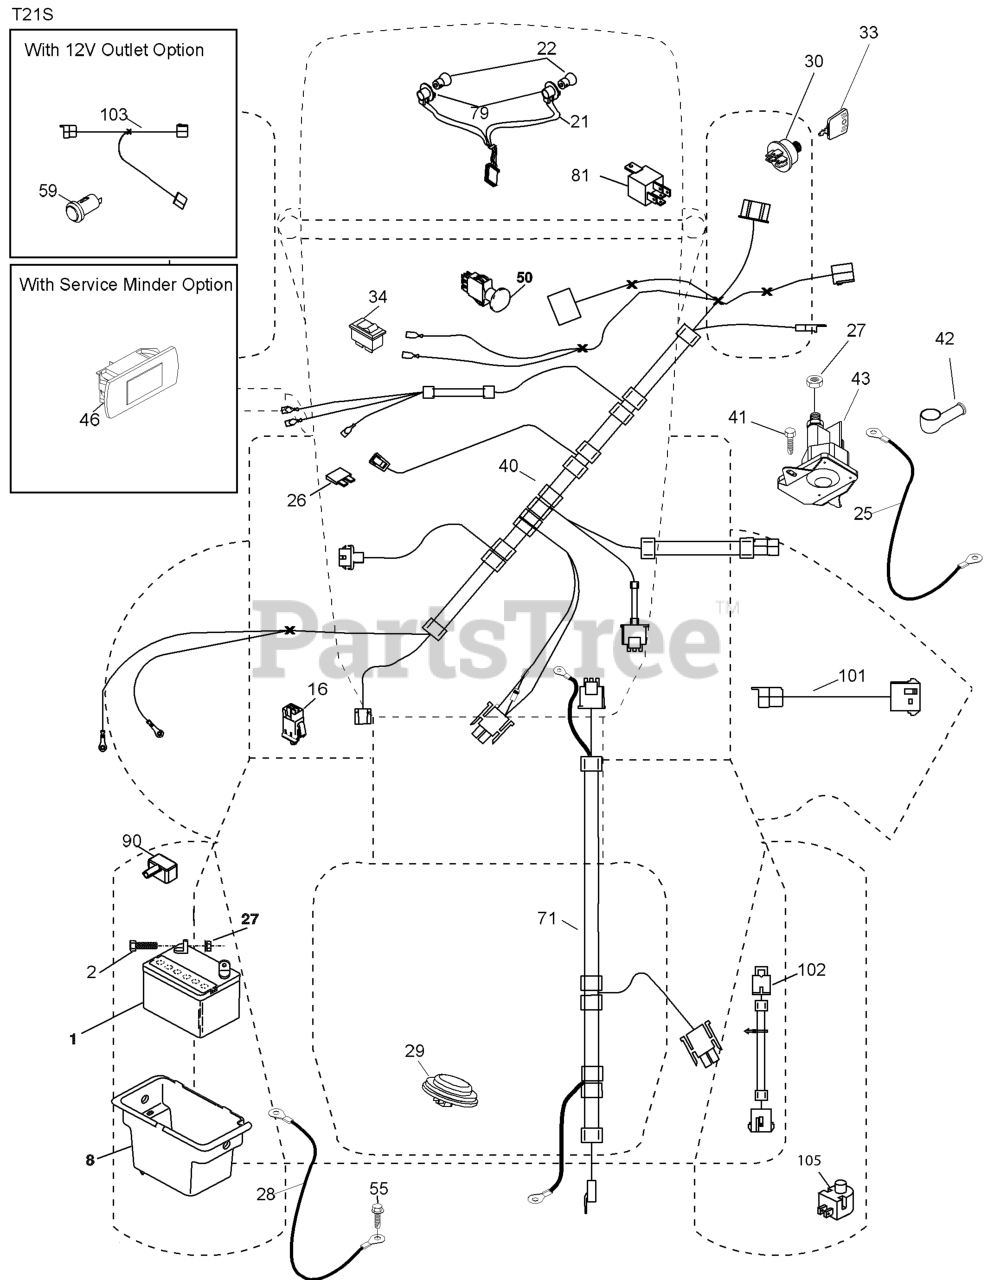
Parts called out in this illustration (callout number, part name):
1	Battery
2	BOLT.HEX.1/4.X.3/4.DICHROMATE
8	BOX.BATTERY.MNT.REAR.L
16	SWITCH INTERLOOK PUSH-IN
21	HARNESS ASSY LIGHT
25	CABLE.STARTER.6G.BL/RED.17.5
26	FUSE 20AMP
27	NUT
28	CABLE.BLACK.18"REAR.BA
29	SWITCH.SEAT.DELTA.OPC.
30	SWITCH.IGN.DELTA.W.LGH.ROS
33	KEY.CHAIN.BLISTER.PACK.GEN.INT
40	HARNESS.IGN.ELE.RELAY.TEX.46"
41	SCREW
42	TERMINAL COVER
43	SOLENOID.W/BRASS.PLUNGER
46	RP.GUAGE.SRVCMNDR.HRMTR.
50	RP.PTO.SWITCH.8 TERMINAL.BLACK
55	SCREW 5/16"
59	OUTLET.12-VOLT
71	HARNESS.IGN.CHASS.TEX.REAR.BAT
79	BULB HOLDER ASM.
81	RELAY HARNESS.SEALED
90	COVER.TERMINAL.BATTERY
101	PIGTAIL.MATNLK.NEW.HAR
102	HARNESS PIGTAIL PCH TEX ROS
103	HARNESS PIGTAIL 12V OUTLET
105	REVERSE SWITCH
